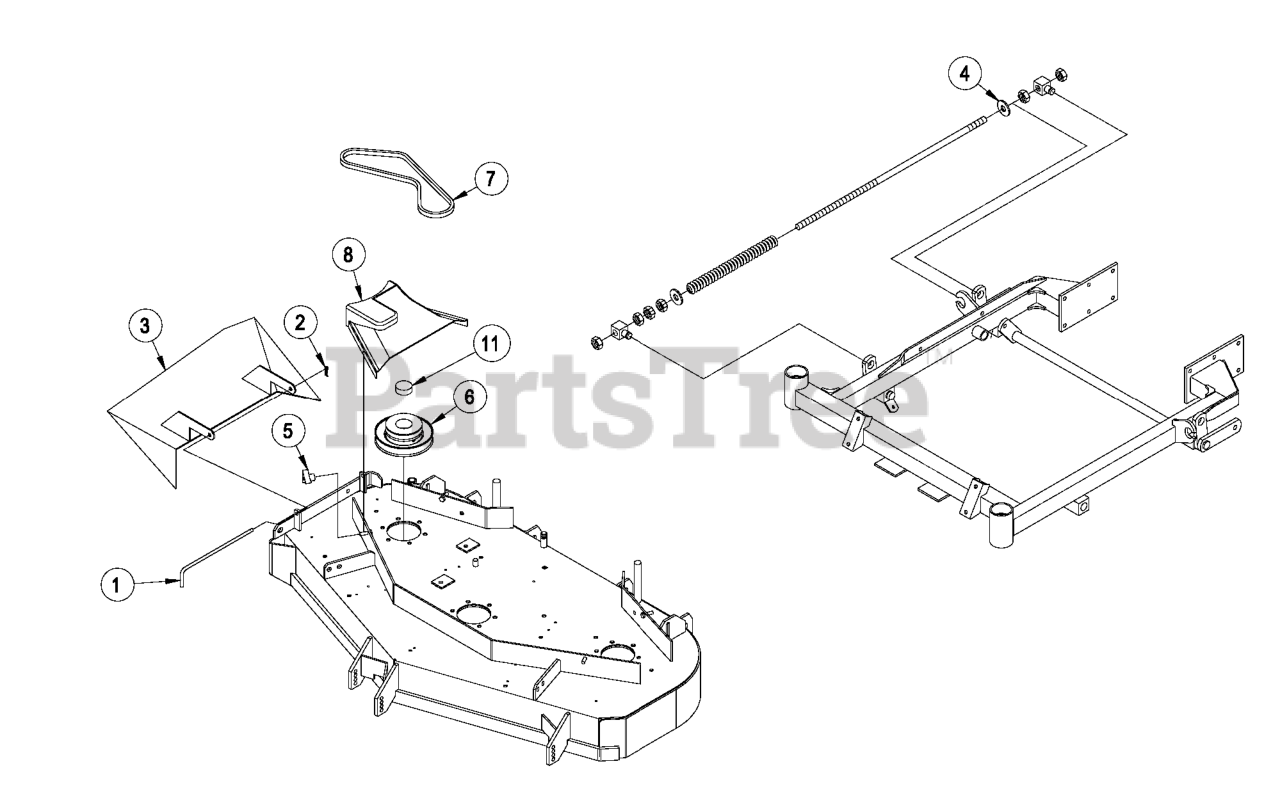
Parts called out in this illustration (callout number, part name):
1	PIN, CHUTE PIVOT PLTD
2	PIN-COTTER
3	Wld, Chute 48" Sd
4	2.25 O.D. Washer
5	KNOB-3 PRONG
6	SHEAVE, BLOWER DR 48"
7	BELT-BLOWER
8	COVER, BELT 44/48
9	Spacer, Counterweight
10	SCREW-HH
11	PLUG, BLACK NYLON 1.75
